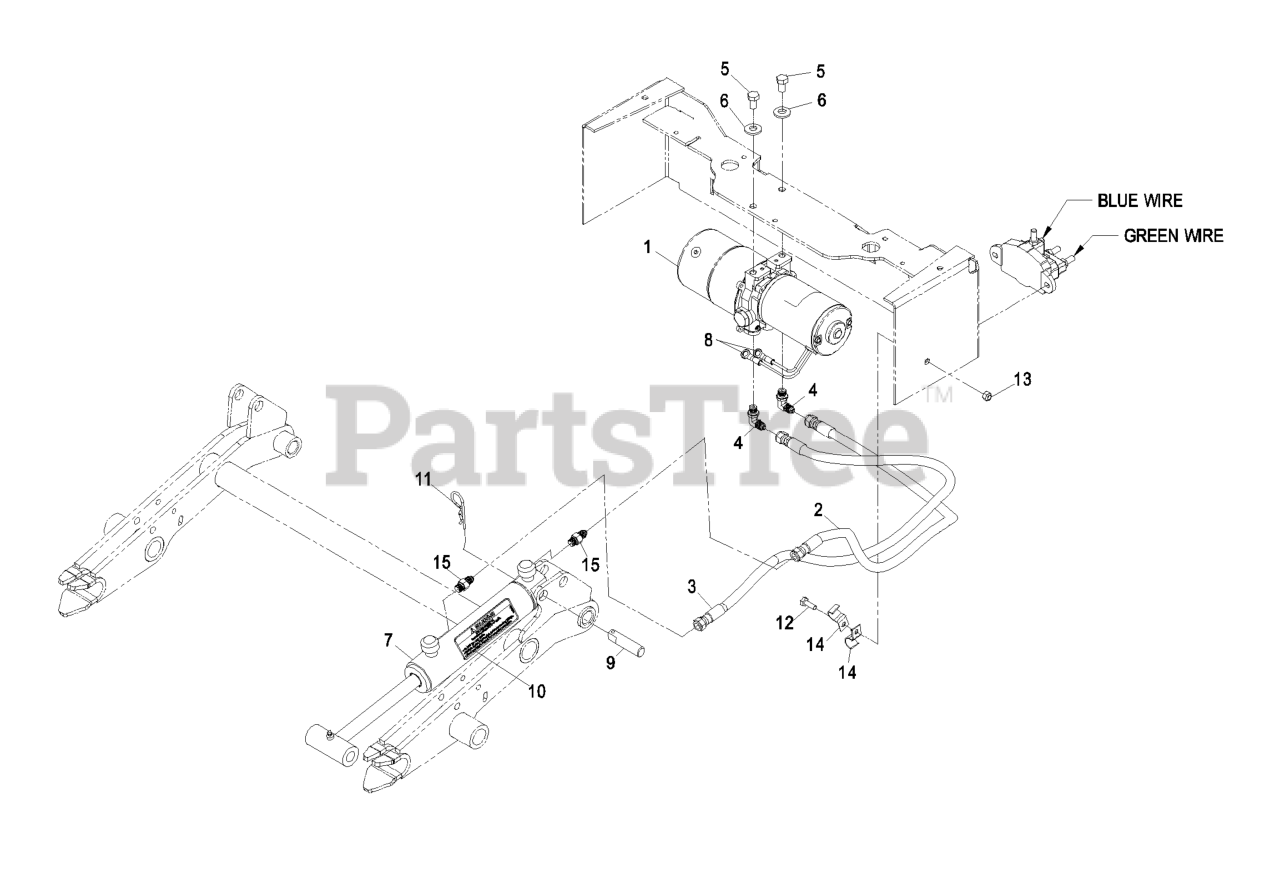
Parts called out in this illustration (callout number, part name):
2	ASM,HYDRAULIC HOSE -4
3	ASM,HYDRAULIC HOSE -4
4	ADAPTER,90 DEG
5	SCREW-HH
6	WASHER-BELLEVILLE
7	ASM,FMZ HYD CYLINDER
8	TERMINAL,RING 5/16" INSUL
9	PIN,CYLINDER MOUNT RR
10	DECAL,HIGH PRESSURE OIL
11	PIN-COTTER
12	SCREW-HH
13	NUT-LOCK, NI
14	CLIP-HALF, LOOM
15	ADAPTER,STRAIGHT ORIFICED
